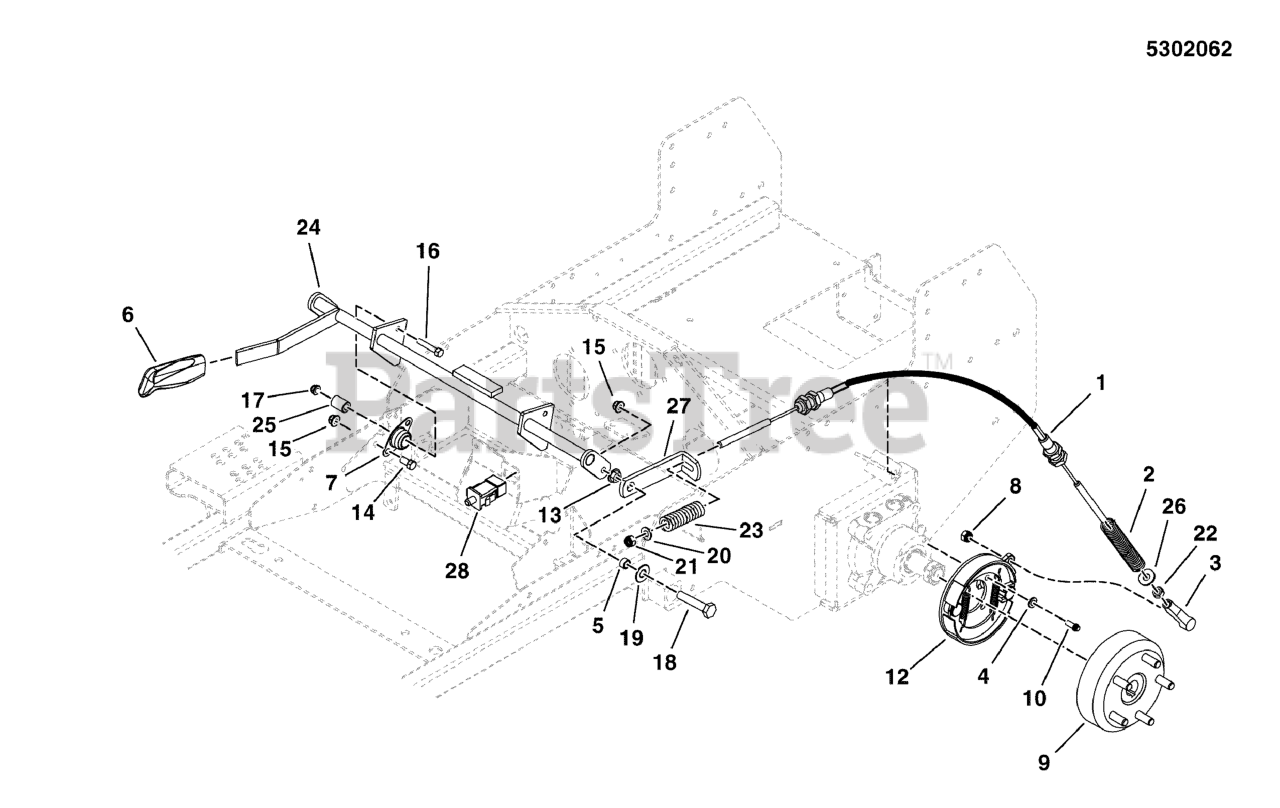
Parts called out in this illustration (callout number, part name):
3	BALL JOINT 5/16-24 LH FEMALE W/STUD, BR
4	WASHER, 5/16 LOCK CZ
5	SPACER, .38 X .50 X .27
6	GRIP, BLACK FLEXIBLE
7	BEARING, BRONZE FLANGE, 3/4
8	NUT, 5/16-24 HEX NYLON LOCK
10	BOLT, 5/16-18 X 3/4 12PT FLANGE - PATCH
13	NUT, 3/8-16 HEX SERRATED FLANGE
14	BOLT, 3/8-16 X 3/4" GD5 CZ
15	NUT, 3/8-16 HEX NYLOCK FLANGE
16	BOLT, 5/16-18 X 1-3/4 GD5 YZ
17	NUT, 5/16-18 HEX NYLOCK FLANGE
18	BOLT, 3/8-16 X 1-1/2" GD5 CZ
19	WASHER, 3/8 SAE
20	WASHER, 5/16" SAE
21	NUT, 5/16-24 HEX NYLON LOCK
22	NUT, 5/16-24 HEX
23	SPRING, BRAKE
24	WELD, SHAFT, PARKING BRAKE - BLK
25	SPACER, .32 X .75 X 1.06
26	WASHER, 5/16 USS
27	LINK, BRAKE LOCK - BLK
28	SWITCH, DP NO/NC SNAP-IN
